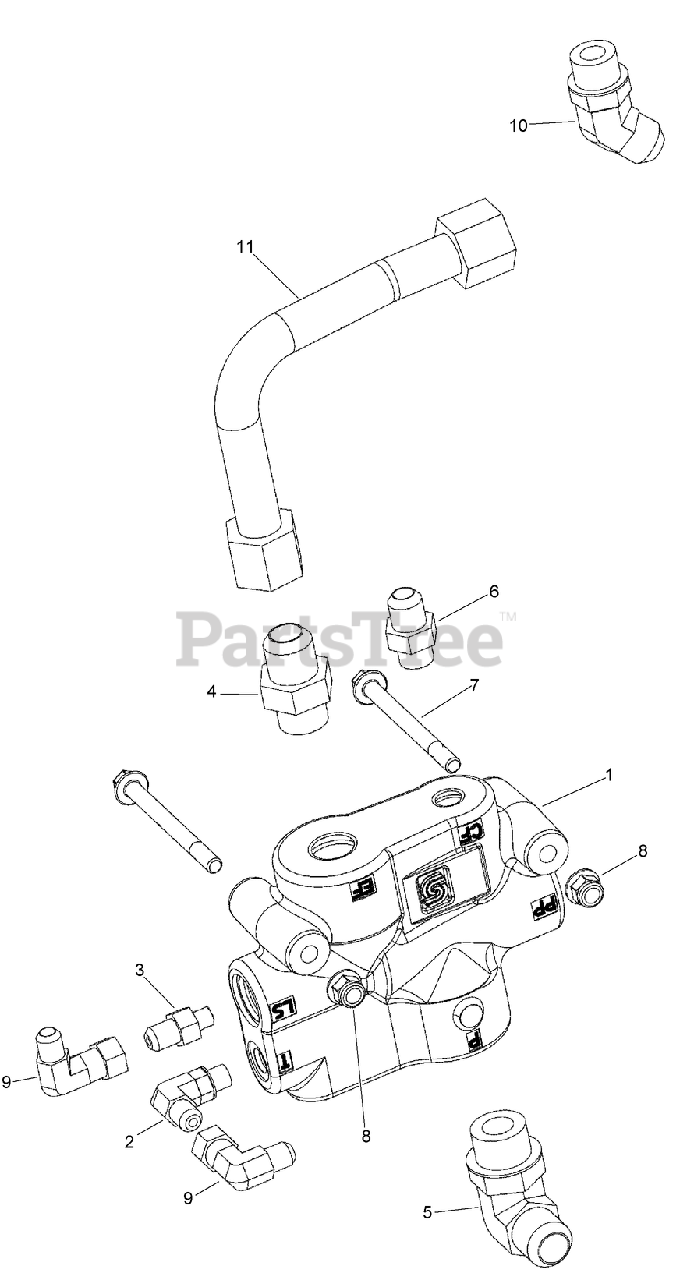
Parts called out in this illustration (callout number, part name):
1	VALVE-FLOW DIVIDER, PRIORITY
2	ELBOW-90, ADJ
3	ADAPTER-STRAIGHT
4	FITTING-STRAIGHT
5	ELBOW-90 Adj 37FL 3/4 Tube
6	CONNECTOR-Str Thd 1/2, 37FL-ORB 1/2
7	SCREW-FLANGE
8	NUT-TORQUE, PREVAILING
9	ELBOW-SWIVEL, 90 DEG
10	FITTING-ELBOW-45 DEG
